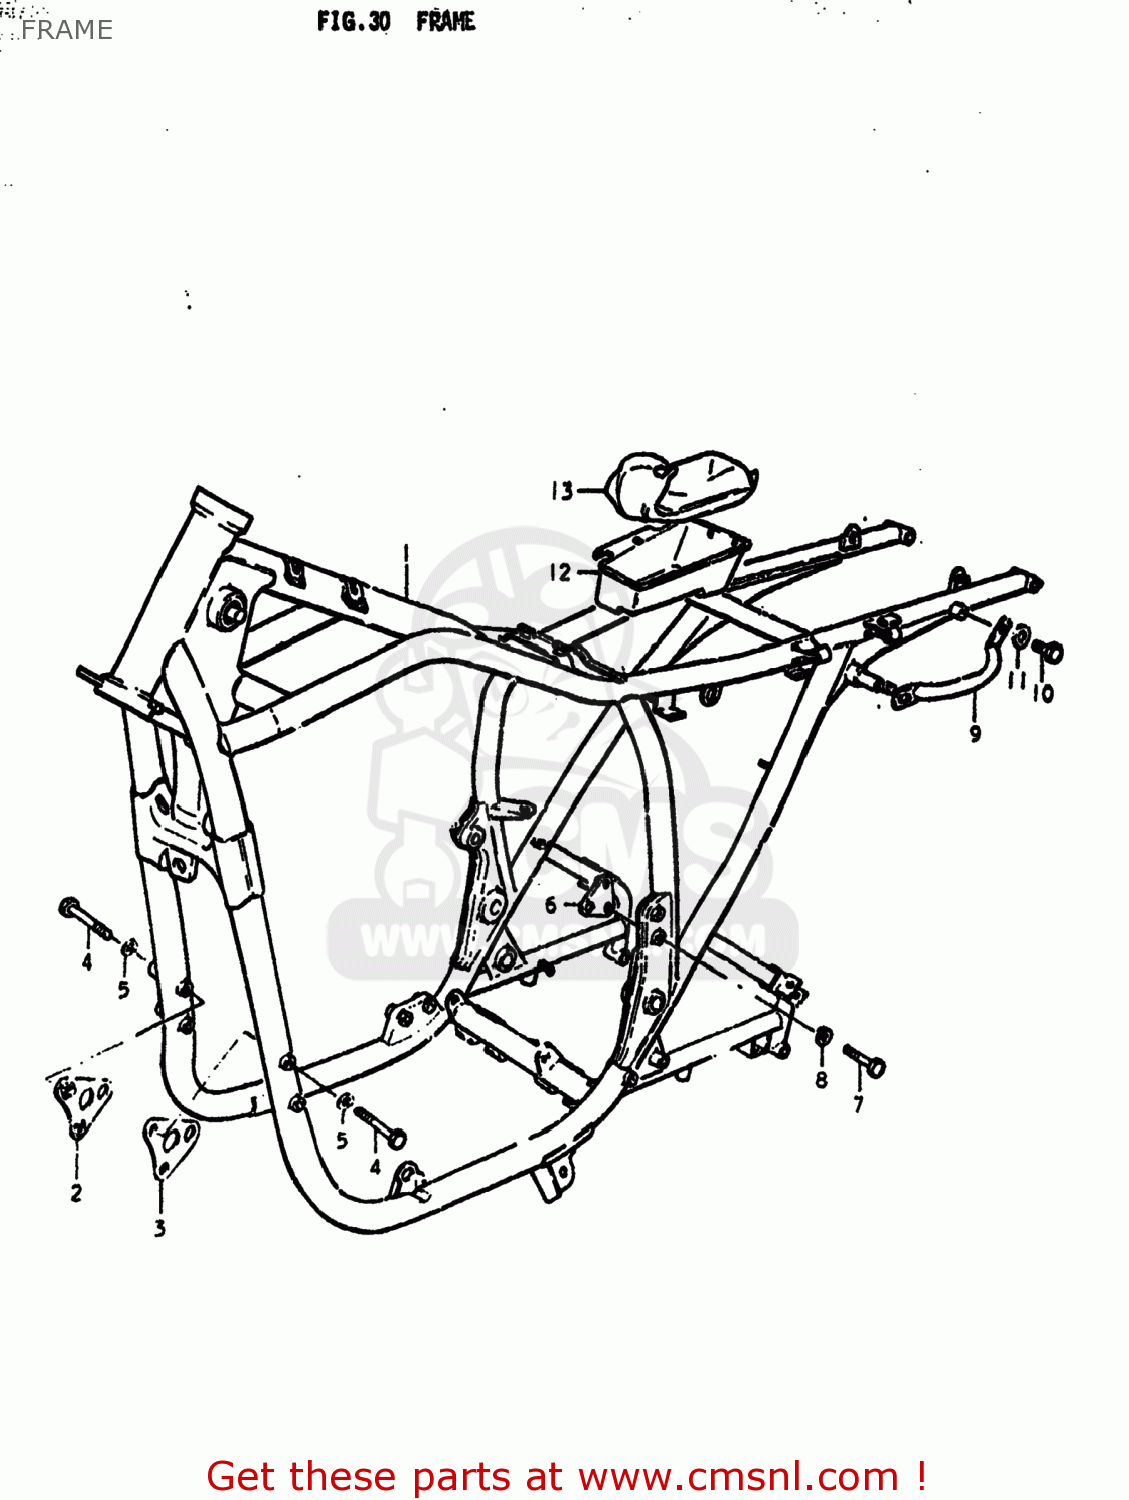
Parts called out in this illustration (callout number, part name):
1	FRAME
2	PLATE,ENGINE MOUNTING
3	PLATE,ENGINE MOUNTING
4	BOLT
5	LOCK WASHER
6	PLATE,ENGINE MOUNTING
7	BOLT 8X40
8	LOCK WASHER
9	GRIP,FRAME HANDLE
10	BOLT
11	WASHER
12	HOLDER,TOOL
13	TOOL SET
